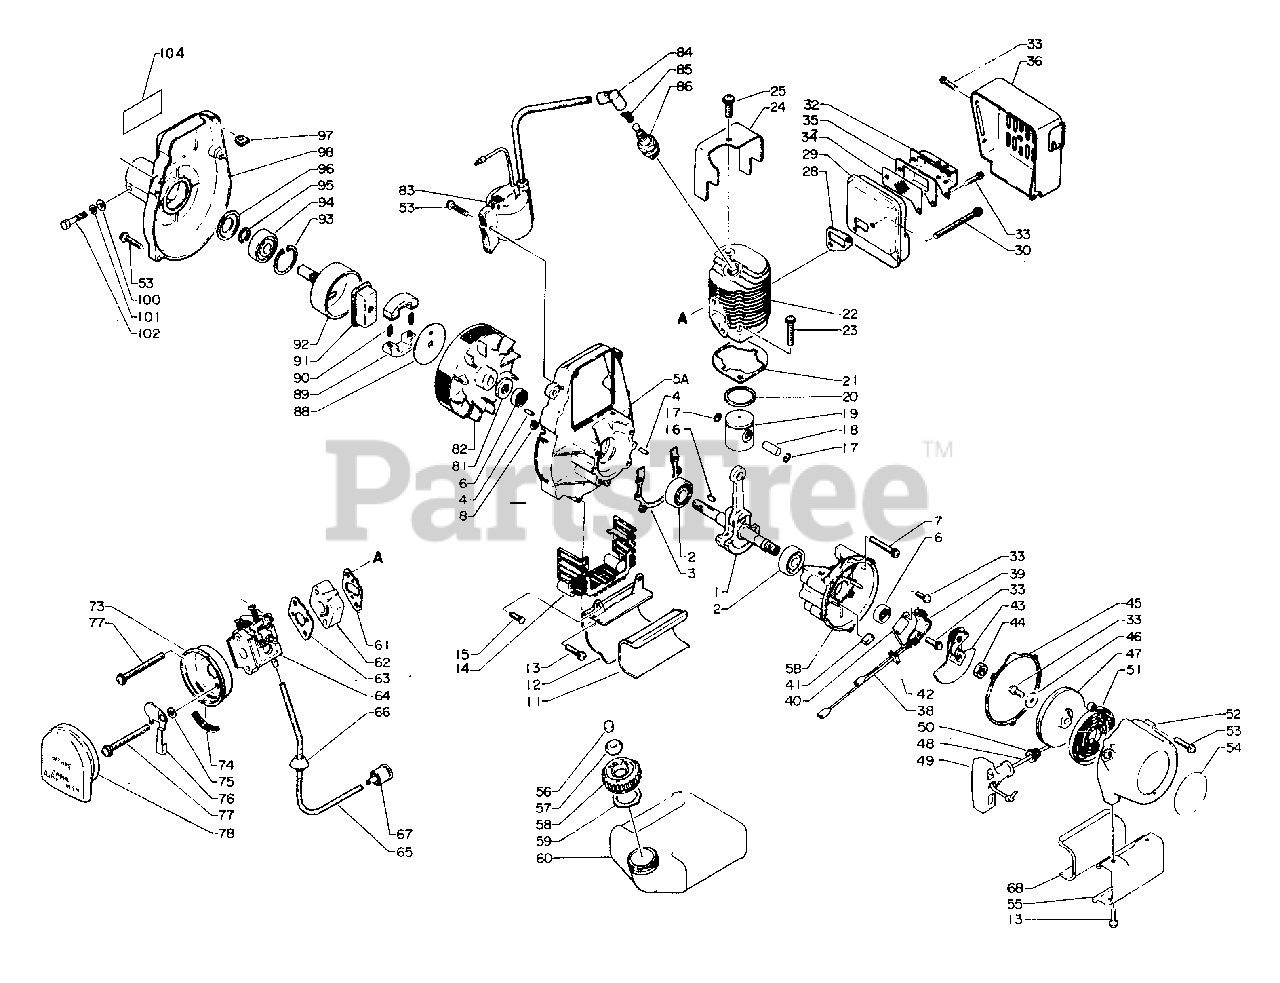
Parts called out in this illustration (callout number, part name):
1	CRANKSHAFT ASSY
2	BEARING, BALL - 6200
3	GASKET, CRANKCASE
4	PIN - LOCATING
5	CRANKCASE KIT
5A	CRANKCASE KIT
5B	CRANKCASE KIT
6	SEAL, OIL
7	SCREW - 5X30
12	BRACKET, FUEL TANK
13	SCREW - 4X14
14	SEAL, DUST
15	SCREW - 4X14 -- TAPPING
17	RING, RETAINING
18	PIN, PISTON
19	PISTON
20	RING, PISTON
21	GASKET, CYLINDER
22	CYLINDER
23	SCREW - 6X22
24	SHIELD, CYLINDER
25	SCREW - 5X10
28	GASKET, EXHAUST
29	CASE, MUFFLER
30	SCREW - 5X40
32	GUIDE, EXHAUST
33	SCREW - 4X10
34	SCREEN, SPARK ARRESTOR
35	RETAINER, SCREEN
36	COVER, MUFFLER
38	LEAD - GROUND
39	CONTACT POINT SET
40	CONDENSER
41	PAD, OIL
43	STARTER PAWL ASSY
45	GASKET, STARTER
45	STARTER ASSY
47	REEL, ROPE
48	ROPE, STARTER - 3X850
49	GRIP, STARTER
50	GUIDE, ROPE
51	SPRING, REWIND
52	CASE, STARTER
53	SCREW - 4X20
54	LABEL - ECHO
55	BRACKET, FUEL TANK
58	CAP
59	GASKET, CAP
60	TANK, FUEL
61	GASKET, INTAKE
62	INSULATOR, INTAKE
63	GASKET, INTAKE
64	CARBURETOR WA-123
65	PIPE - 3X5X195 -- BLACK
67	FILTER, FUEL
73	CASE, AIR FILTER
75	WASHER - 5
76	SHUTTER, CHOKE
77	SCREW - 5X57
78	FILTER, AIR
82	FLYWHEEL
83	COIL, IGNITION
84	CAP, SPARK PLUG
85	TERMINAL, SPARK PLUG CAP
86	SPARK PLUG -- CJ-8
88	PLATE, CLUTCH
89	SHOE, CLUTCH
90	SPRING, CLUTCH
91	HUB, CLUTCH
92	DRUM, CLUTCH
93	RING, RETAINING - 32
94	BEARING, BALL - 6201
95	RING, RETAINING - 12
96	RETAINER, PIPE
98	CASE, FAN
100	WASHER - 5
101	LOCKWASHER - 5
102	BOLT - 5X20
104	LABEL
